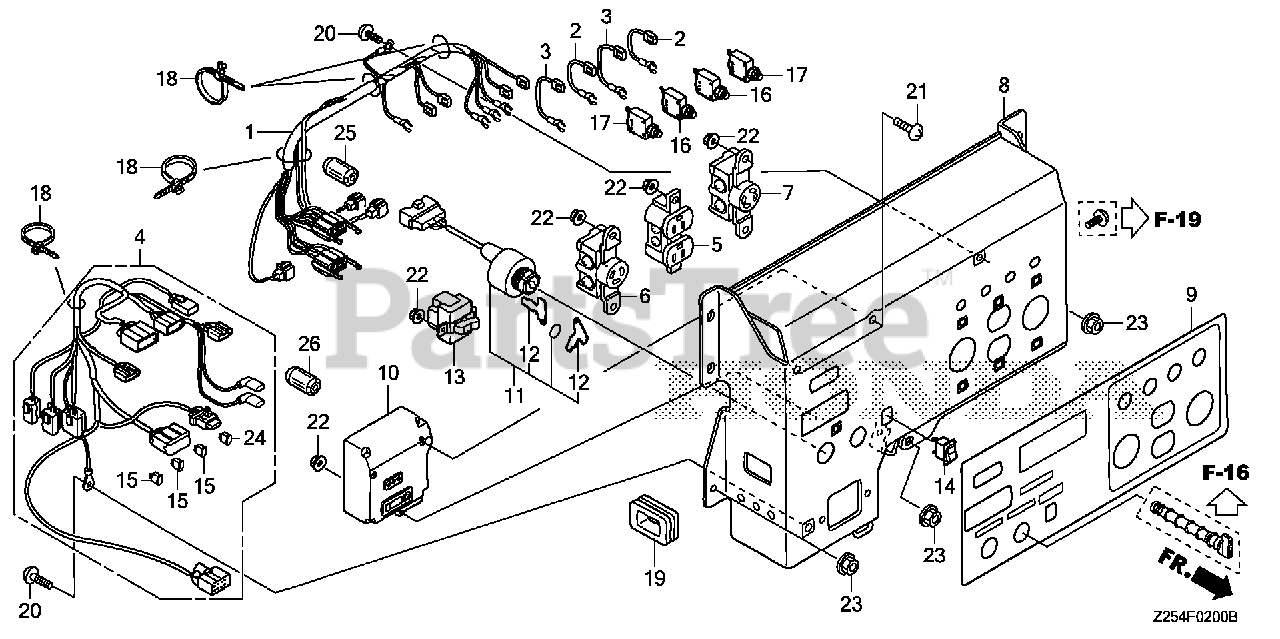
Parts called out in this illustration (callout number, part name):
1	WIRE HARNESS ASSY., MAIN
2	SUB-WIRE ASSY. (A)
3	SUB-WIRE ASSY. (D)
4	WIRE HARNESS ASSY., CONTROL
5	RECEPTACLE (20A/125V) (MATSUSHITA)
6	RECEPTACLE (30A/125V)
7	RECEPTACLE (30A/125-250V)
8	PANEL, CONTROL
9	MARK, PANEL
10	CONTROL UNIT ASSY., GENERATOR
11	SWITCH ASSY., COMBINATION
12	KEY (HONDALOCK)
13	SWITCH ASSY., VOLT CHANGE
14	SWITCH, AUTO-THROTTLE (OTAX)
15	FUSE, BLADE (1A)
16	PROTECTOR, CIRCUIT (20A) (WHITE)(TYCO)
16	PROTECTOR, CIRCUIT (20A) (BLACK)(JOEMEX)
17	PROTECTOR, CIRCUIT (30A) (WHITE)
17	PROTECTOR, CIRCUIT (30A) (BLACK)
18	STRAP, CABLE (105MM) (BLACK)
19	GROMMET, CONTROL HARNESS
20	SCREW, PAN (5X8)
21	SCREW, PAN (5X12)
22	NUT, FLANGE (4MM)
23	NUT, FLANGE (6MM)
24	FUSE, BLADE (15A)
25	FILTER, SUB NOISE (AC)
26	FILTER, SUB NOISE (AC)
